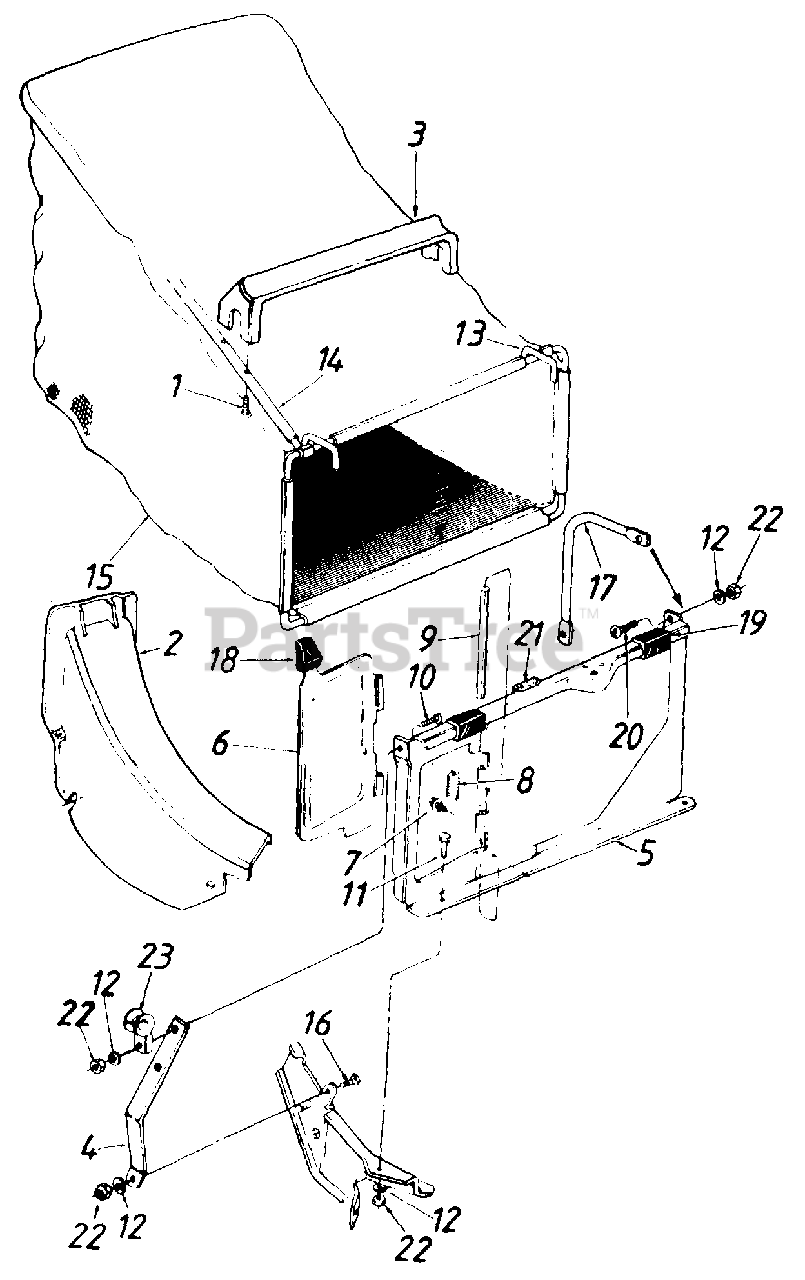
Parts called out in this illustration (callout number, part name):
1	Hex AB-Tap Scr. #12 x 1.25" Lg
2	Rear Discharge Chute Ass'y.
3	Bag Handle
7	Hex B-Tap Scr. #10 x .38"
8	Torsion Spring
9	Pivot Pin
10	Truss Mach. Scr. 1/4-20 x 3/4" Lg.
11	Hex Bolt 1/4-20 x .50" Lg.
12	L-Wash. 1/4" I.D.
15	21" Rear Discharge Grass Bag
16	Hex Bolt 1/4-20 x .62" Lg.
17	Catcher Panel Support Arm
18	Door Grip
19	Panel Clip
20	Truss Mach. Scr. 1/4-20 x .62" Lg.
21	Foam Strip
22	Hex Nut 1/4-20 Thd.
23	Rope Guide
